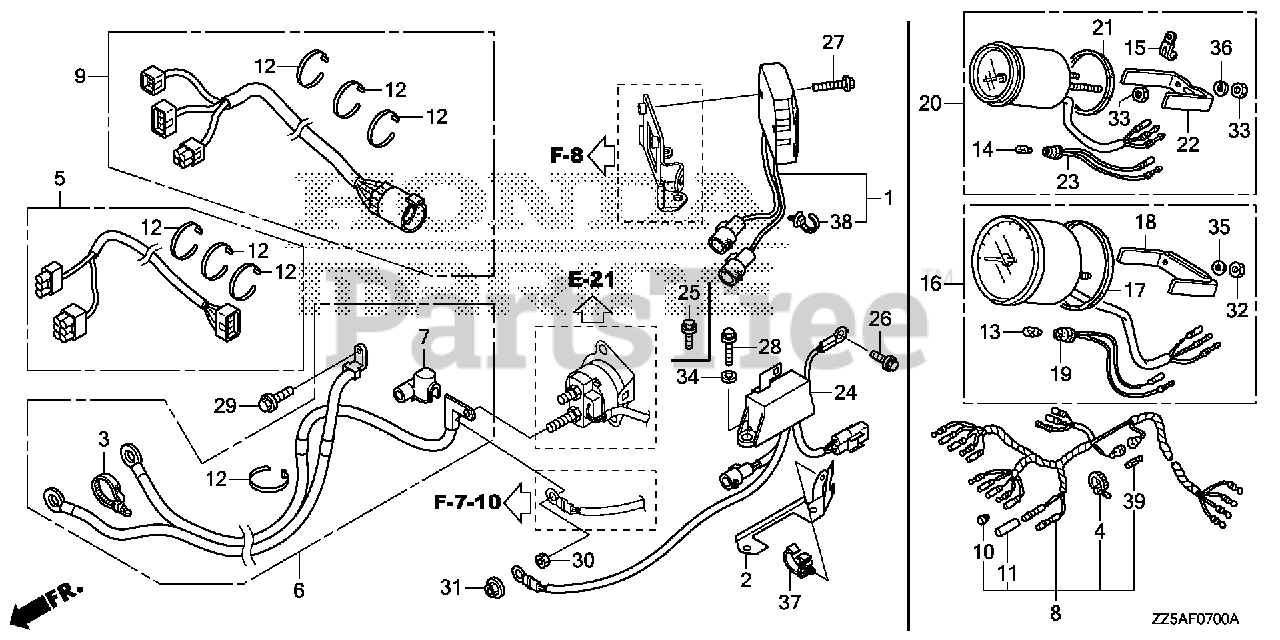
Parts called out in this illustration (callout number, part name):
1	RECTIFIER ASSY., REGULATOR
2	BRACKET A, HARNESS CLIP
3	BAND, WIRE (165MM) (BLACK)
6	CABLE ASSY., STARTER
7	COVER, TERMINAL
12	TIE, CABLE (2.4X92) (NATURAL)
25	BOLT, FLANGE (6X12) (CT200)
27	BOLT, FLANGE (6X25)
29	BOLT, FLANGE (8X18)
30	NUT, HEX. (6MM)
37	CLIP, WIRE HARNESS
38	CLIP, HARNESS BAND (96.9MM) (NATURAL)
